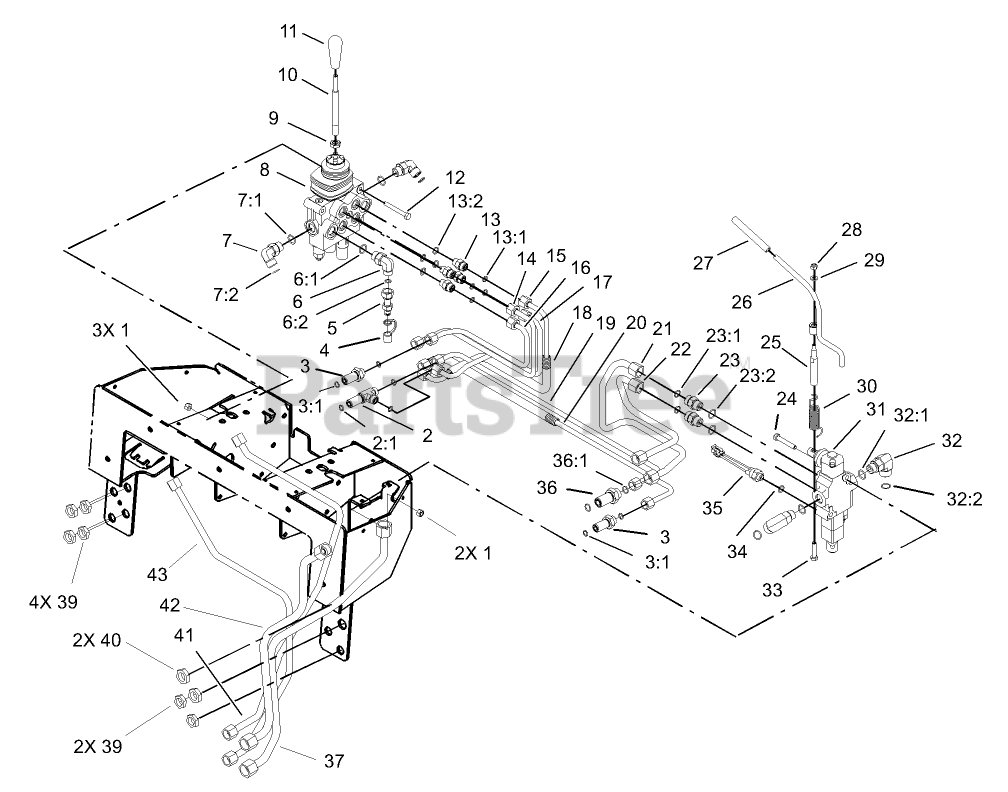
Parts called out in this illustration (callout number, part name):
1	NUT-LOCK, NI
2	FITTING-TEE, BULKHEAD
2:1	O-RING
3	FITTING-STRAIGHT, BULKHEAD
3:1	O-RING
4	CAP-DUST
5	NIPPLE-TEST
6	FITTING-HYD, 90 DEG
6:1	O-RING
6:2	O-RING
7	FITTING-ELBOW-90 DEG
7:1	O-RING
7:2	O-RING
8	VALVE-2 SPOOL
10	SHAFT-HANDLE, LIFT/TILT
11	KNOB-TAPERED
12	SCREW-HH
13	FITTING-STRAIGHT
13:1	O-RING
13:2	O-RING
14	HYD TUBE ASM
15	HYD TUBE ASM
16	HYD TUBE ASM
17	HYD TUBE ASM
18	CONDUIT-CONVOLUTED
19	HYD TUBE ASM
20	HYD TUBE ASM
21	HYD TUBE ASM
22	HYD TUBE ASM
23	FITTING-STRAIGHT
23:1	O-RING
23:2	O-RING
24	SCREW-HH
25	SPACER-HIFLO
26	AUXILIARY LEVER ASM
27	CAP-ROD, TILT
28	NUT-LOCK, NI
29	WASHER-FLAT
30	SPRING-TORSION
31	1 SPOOL VALVE ASM
32	Fitting-Elbow, 90 DEG
32:1	O-RING
32:2	O-RING
33	SCREW
34	O-RING
35	SWITCH-BALL
36	FITTING-BULKHEAD
36:1	O-RING
37	HYD Tube ASM
39	NUT-LOCK
40	NUT-BULKHEAD
41	HYD Tube ASM
42	TUBE-HYD
43	HYD Tube ASM
